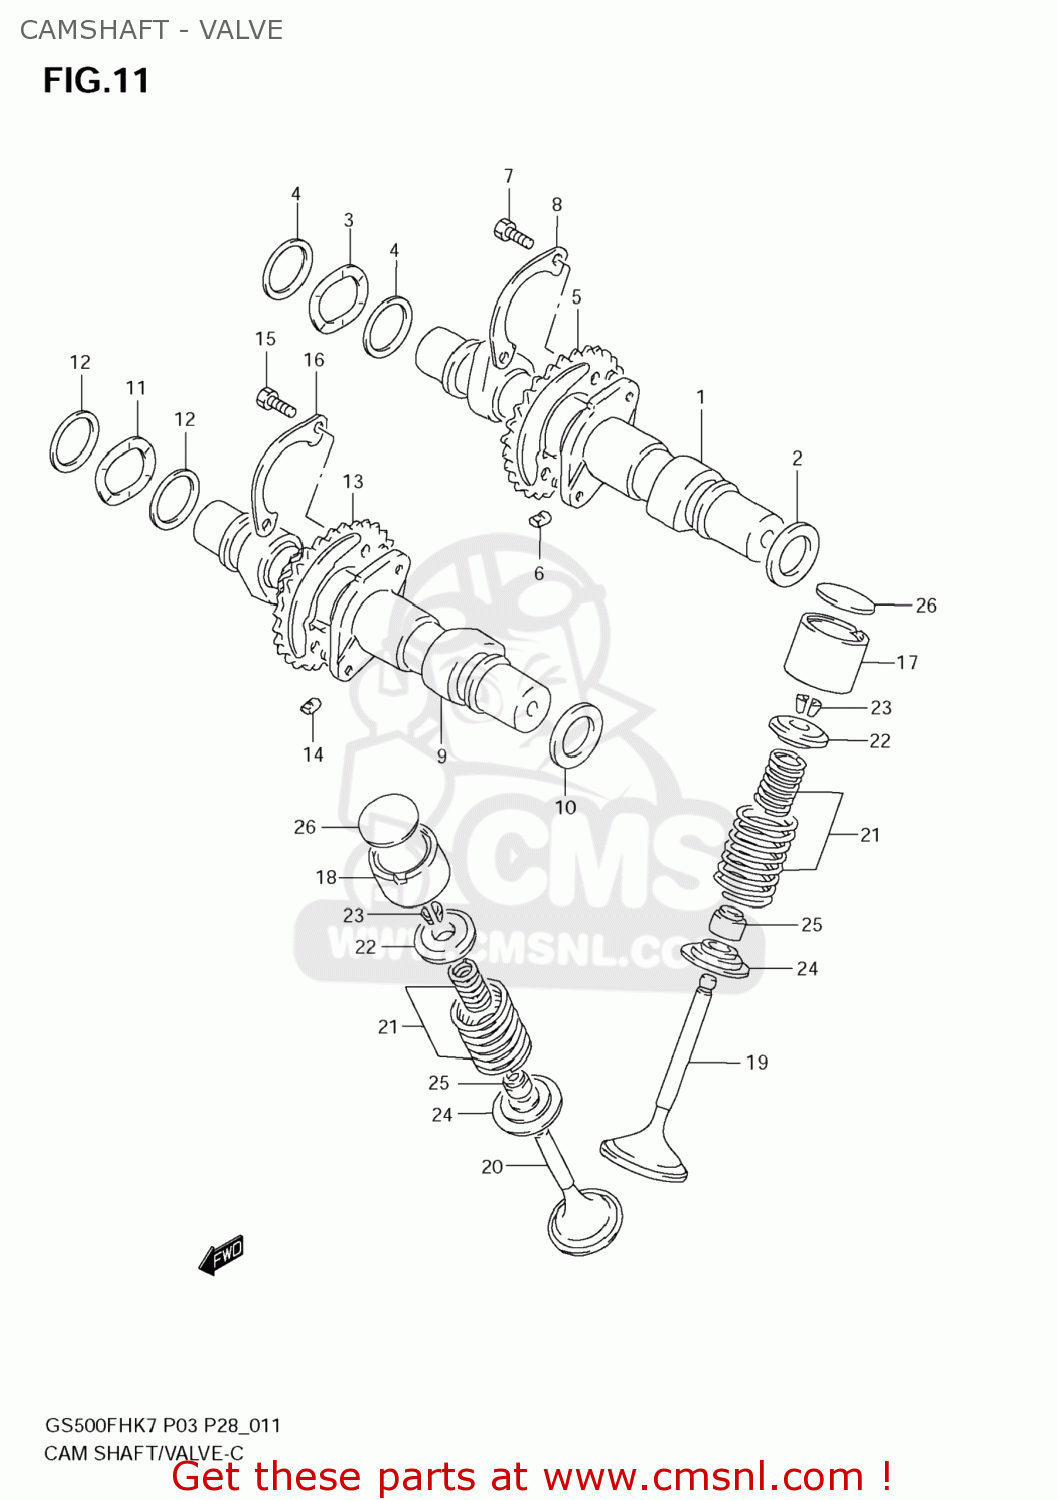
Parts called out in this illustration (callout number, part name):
1	CAMSHAFT SET,INTAKE
2	SHIM(22X30X1)
3	WASHER
4	SHIM(22X28X0.7)
5	SPROCKET,CAMSHAFT INTAKE
6	PIN,SPROCKET
7	BOLT(6X12.5)
8	WASHER,SPROCKET
9	CAMSHAFT SET,EXHAUST
10	SHIM(22X30X1)
11	WASHER
12	SHIM(22X28X0.7)
13	SPROCKET,EXHAUST CAM(NT:30)
14	PIN,SPROCKET
15	BOLT(6X12.5)
16	WASHER,SPROCKET
17	TAPPET
18	TAPPET,INTAKE
19	VALVE,INTAKE
20	VALVE,EXHAUST
21	SPRING SET,VALVE
22	RETAINER,VALVE SPRING
23	COTTER VALVE
24	SEAT,VALVE SPRING
25	SEAL,OIL(7X14.4X9)
26	SHIM,TAPPET(T:2.15)
